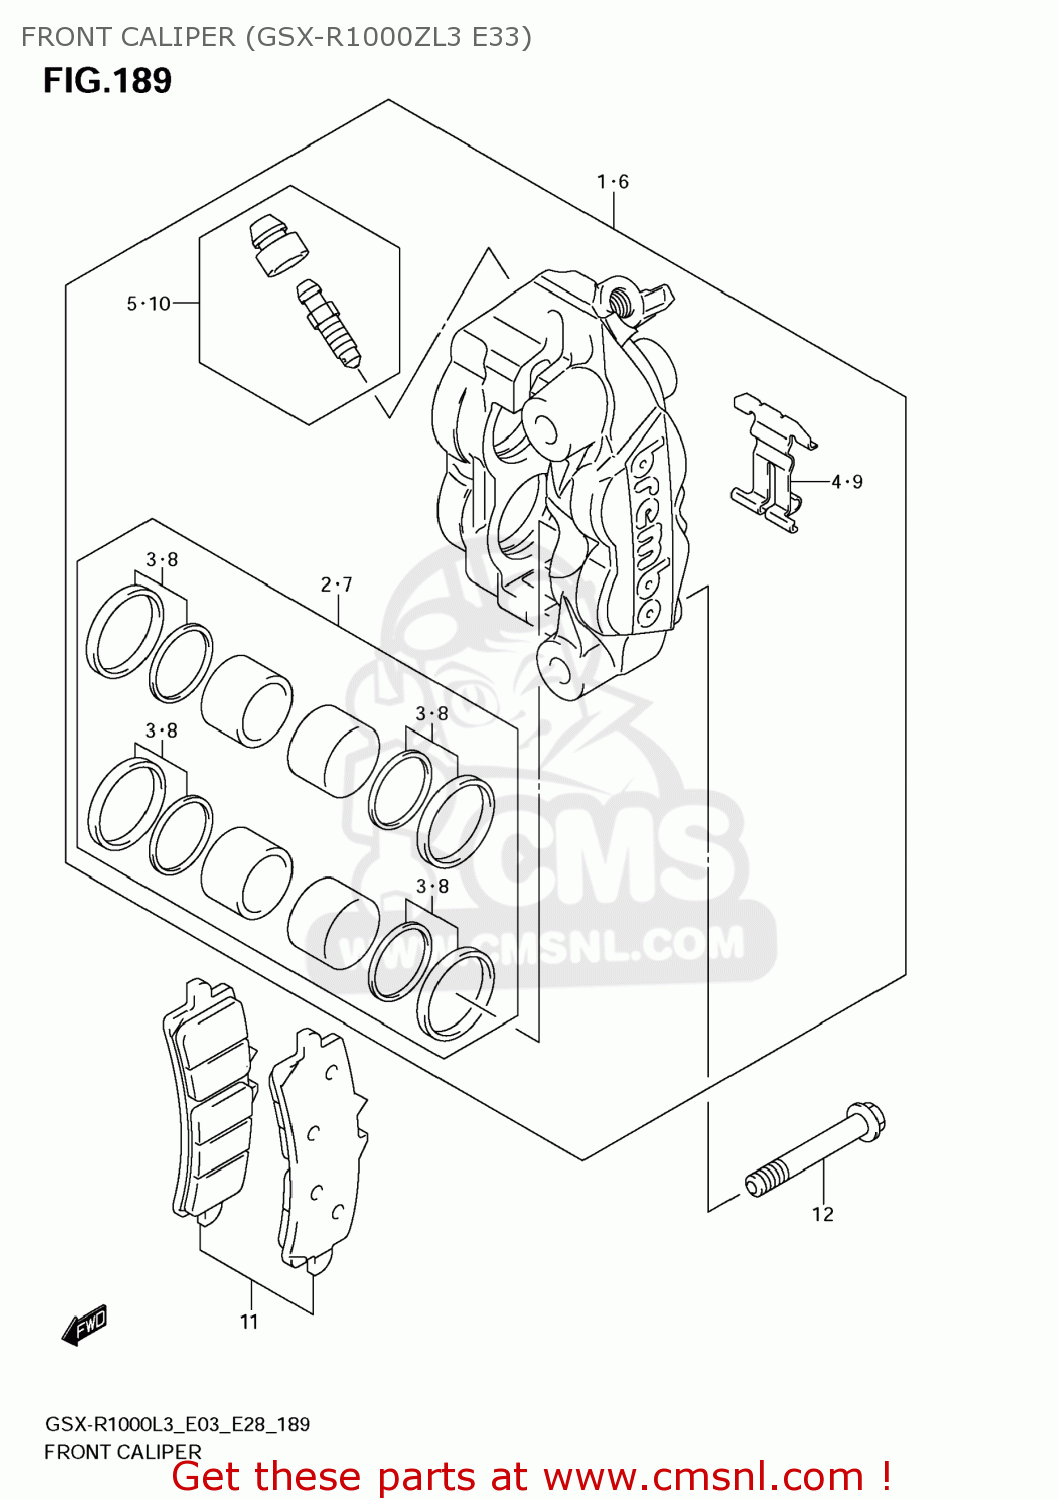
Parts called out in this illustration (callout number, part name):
1	CALIPER ASSY,FR,R
2	PISTON SET
3	SEAL SET,PISTON
4	SPRING
5	BLEEDER SET
6	CALIPER ASSY,FR,L
7	PISTON SET
8	SEAL SET,PISTON
9	SPRING
10	BLEEDER SET
11	PAD SET(T:4.0) (NAS)
12	BOLT(10X70)
